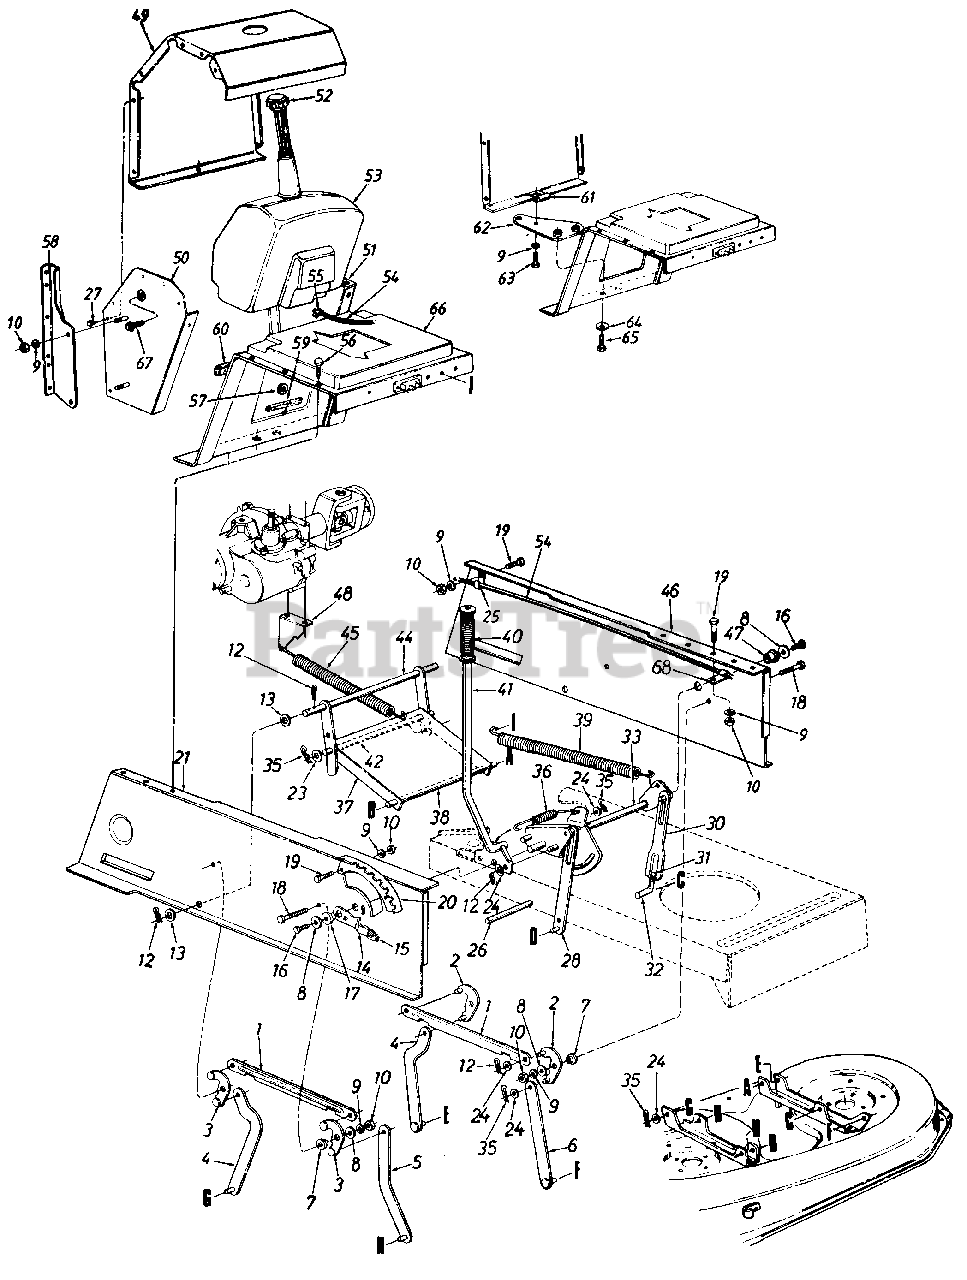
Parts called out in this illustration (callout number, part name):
1	Connecting Rod
2	Pivot Link Ass'y. L.H.
3	Pivot Link Ass'y. R.H.
7	Shld. Spacer .3/8" I.D.
8	Fl-Wash. .344" I.D. x 1.125"
9	L-Wash. 5/16" I.D.
10	Hex Nut 5/16-18 Thd.
12	Cotter Pin 1/8" Dia.
13	Fl-Wash. .635" I.D. x 1.0" O.D.
14	Deck Lift Down Stop
15	Knob
16	Hex Wash. TT-Tap Scr. 5/16-18 x .75" Lg.
17	Flange Brg. .63" I.D.
18	Hex Wash. TT-Tap Scr. 5/16-18 x.875" Lg.
19	Hex Bolt 5/16-18 x .75" Lg.
20	Index Brkt.
21	Upper Frame R.H.
23	Fl-Wash. .385" I.D. x .87" O.D.
24	Fl-Wash. .531" I.D. x .98" O.D.
25	Clamp
26	Running Board Rod
27	Truss Mach. Scr. #10 x 5" Lg.
31	Hex Jam Nut 1/2-20 Thd. (Grade 5)
32	Lift Link Adjuster
33	Lift Shaft Ass'y.
35	Inter. Cotter Pin 3/8" Dia.
36	Extension Spring
37	Stabilizer Bracket
38	Shaft 1/2" Dia. x 10.28" Lg.
39	Extension Spring
40	Grip
41	Deck Lift Handle Ass'y.
42	Shaft 3/8" Dia. x 9.34" Lg.
44	Stabilizer Shaft Ass'y.
45	Extension Spring 7.58" Lg.
46	Upper Frame L.H.
47	Flange Brg. .632" I.D.
48	Spring Retainer Brkt.
49	Gas Tank Housing
50	Side Panel Ass'y. R.H.
53	Gas Tank
54	Fuel Line
55	Hose Clamp
56	Hex Wash. AB-Tap 5/16 x .75" Lg.
57	Rubber Grommet
58	Mtg. Brkt. R.H.
59	Trim Strip
60	Foam Strip
61	Speed Nut
62	Hitch Bar Ass'y.
63	Hex Bolt 5/16-18 x 1.0" Lg. (Grade 5)
64	Bell-Wash. .38" I.D. x .88"
65	Hex Wash. Tap Scr. 3/8-16 x .75" Lg.
66	Hitch Plate
67	Hex Wash. Hd. Tap Scr. 1/4-20 x.38" Lg.
68	Clamp
